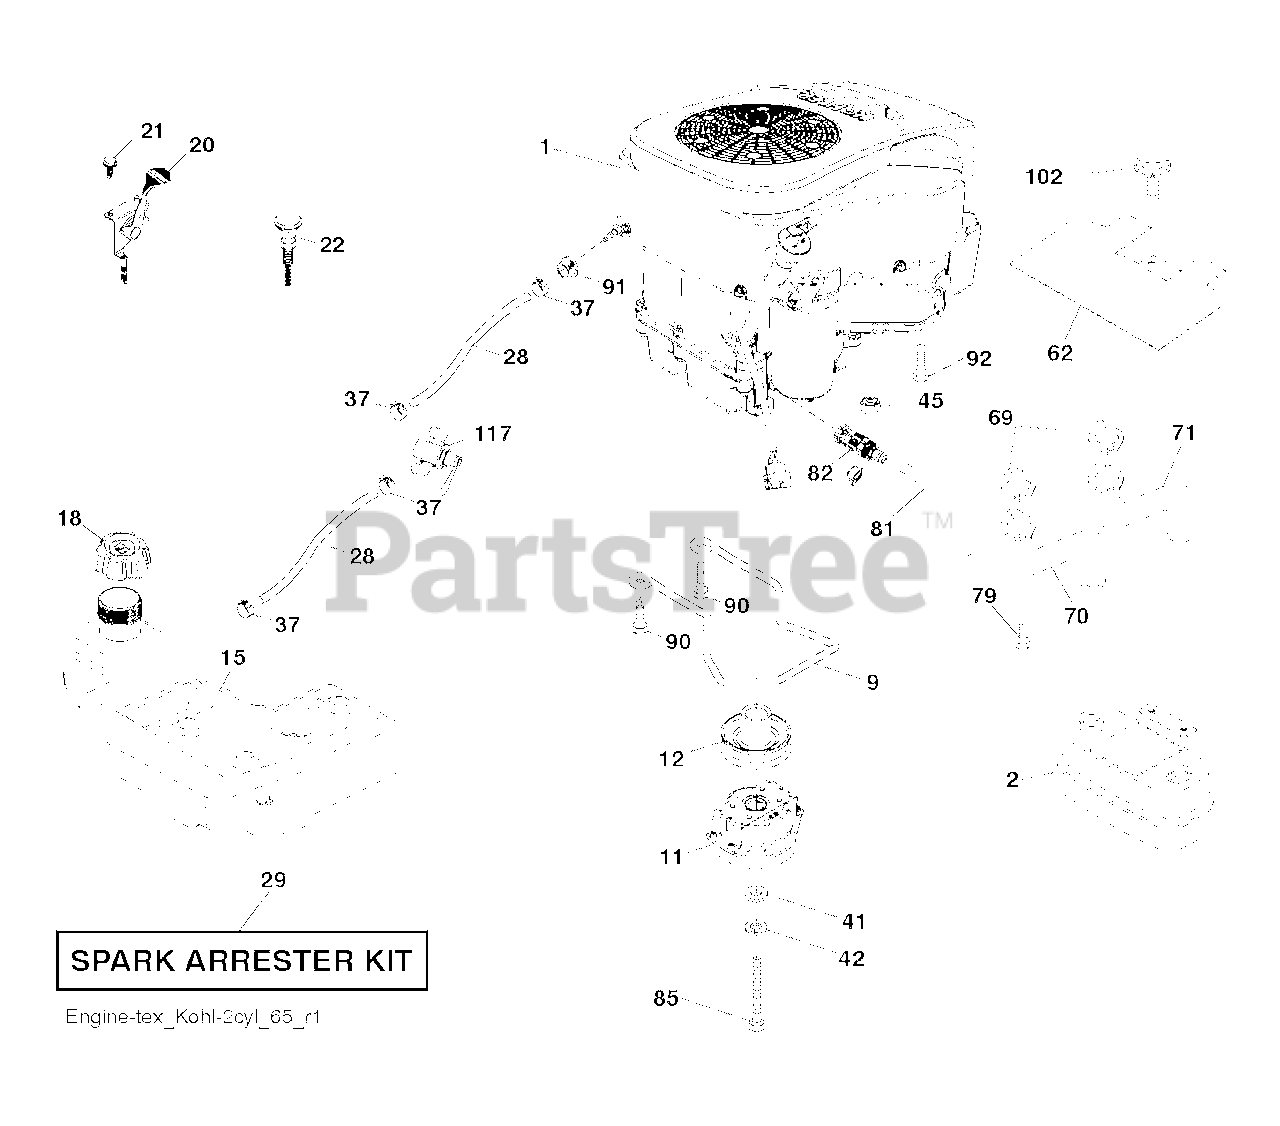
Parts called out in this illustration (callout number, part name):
2	Muffler Assembly, Twin MN
9	KEEPER.BELT.ENG.4.25"2.BLT.431
11	CLUTCH.OGURA.5.0PD.GT1.5A-EH01
12	PULLEY ENGINE
15	TANK.ASM.FUEL.4R.GAL.EPA.17
18	CAP ASSY FUEL 3" GRAY
20	THROTTLE CONTROL
21	SCREW.#10 X 0.750.BOS
22	CONTROL.CHOKE.ERGO.PUSH-IN.BLA
28	LINE.FUEL.64"REAR.EMIS
29	KIT.SPARK ARRESTOR 794945 B&S
37	HOSE CLAMP
42	WASHER 7/16 LOCK
45	NUT
62	SHIELD.HEAT.MUFFLER
69	GASKET.EXHAUST.KOHL.CV18-CV26
70	PIPE.EXHAUST.LH.CV18/20
71	PIPE.EXHAUST.RH.CV18/20
79	SCREW.SOCKET HD.5/16-1
81	TUBE, DRAIN OIL ASM.
82	VALUE.OIL.DRAIN
85	BOLT.HEX.7/16-20X3.GR5.YELLOW
90	SCREW 3/8-16X1
91	BUSHING.1.375OD
92	SCREW 3/8-16X1
102	SCREW
117	VALVE FUEL RESERVE
